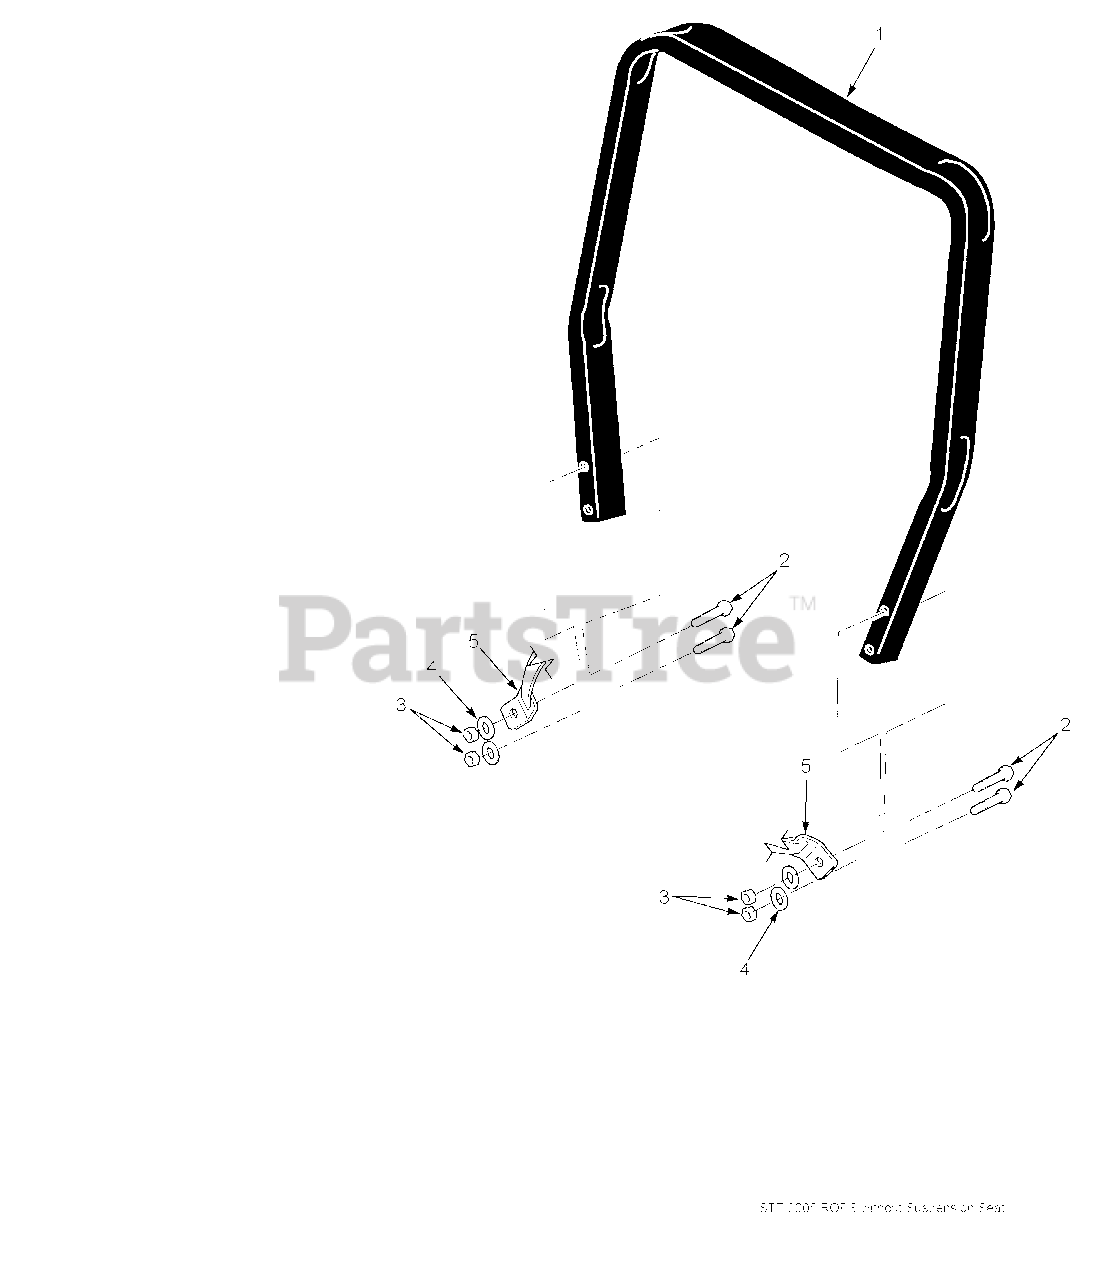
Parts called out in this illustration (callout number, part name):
1	STT, ROPS
2	Bolt, Hex Head 1/2-13 x 4-1/2"
3	Nut, Center Lock 1/2-13
4	Flatwasher, 1/2-.562 x 1.375 x .109
5	Seat Belt
